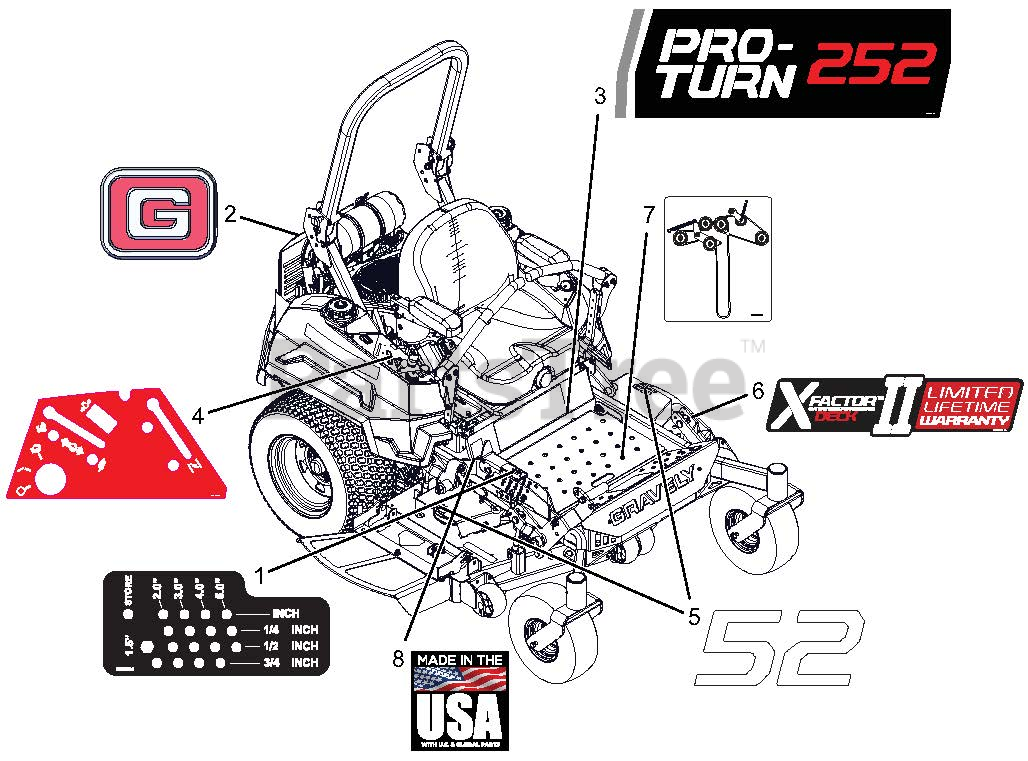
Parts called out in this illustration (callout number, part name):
1	DECAL, HEIGHT OF CUT
2	DECAL, GRAVELY BRAND
3	DECAL, PRO-TURN 252
4	DECAL, EFI CONTROL PANEL
5	DECAL, 52"
6	DECAL, X-FACTOR DECK
7	DCL,BELT ROUTE-RH V-SIDE IDLER
8	DECAL, MADE IN USA
